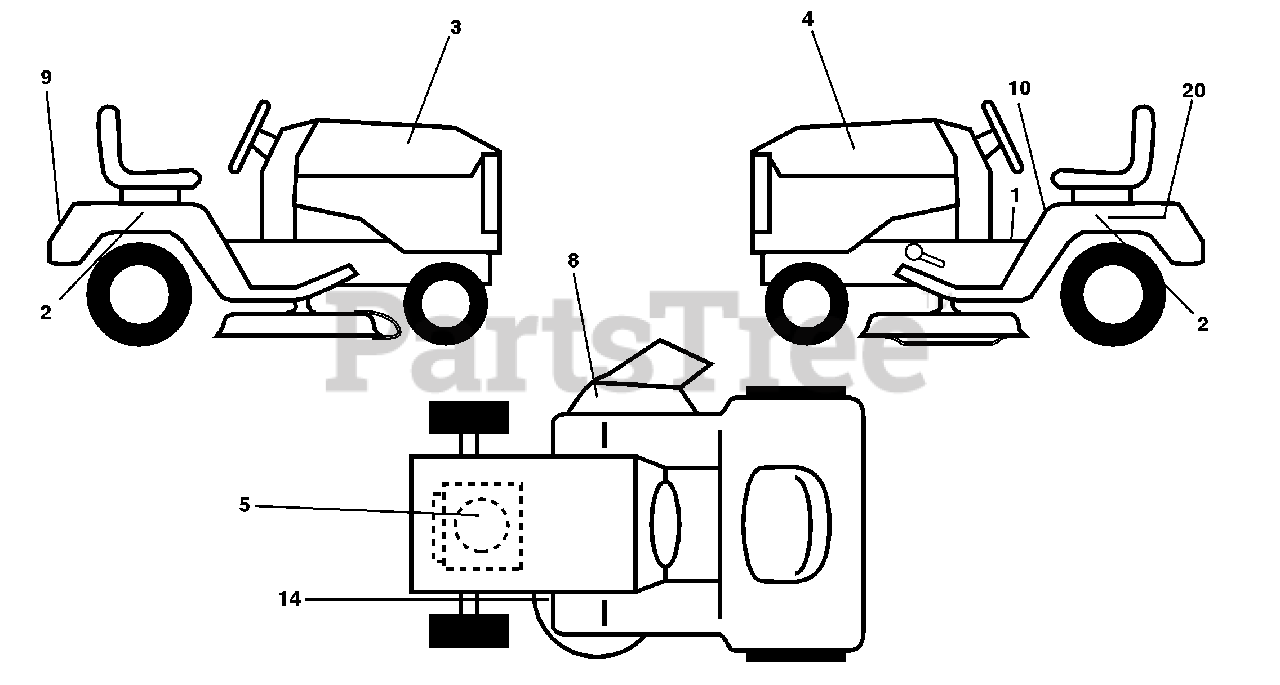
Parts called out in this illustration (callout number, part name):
1	Decal Oper. Step Thru Eng/Fr
2	Decal Fender Auto Husq Radius
3	Decal Hood RH
4	Decal Hood LH
5	Decal HP Engine
8	Decal Warning
9	Decal Fender Husq
10	Decal Fender Danger Eng/Fr
14	Decal V-Belt Schematic
20	Decal Bat Dan/Psn
MK380	Mulcher Kit with Blades
